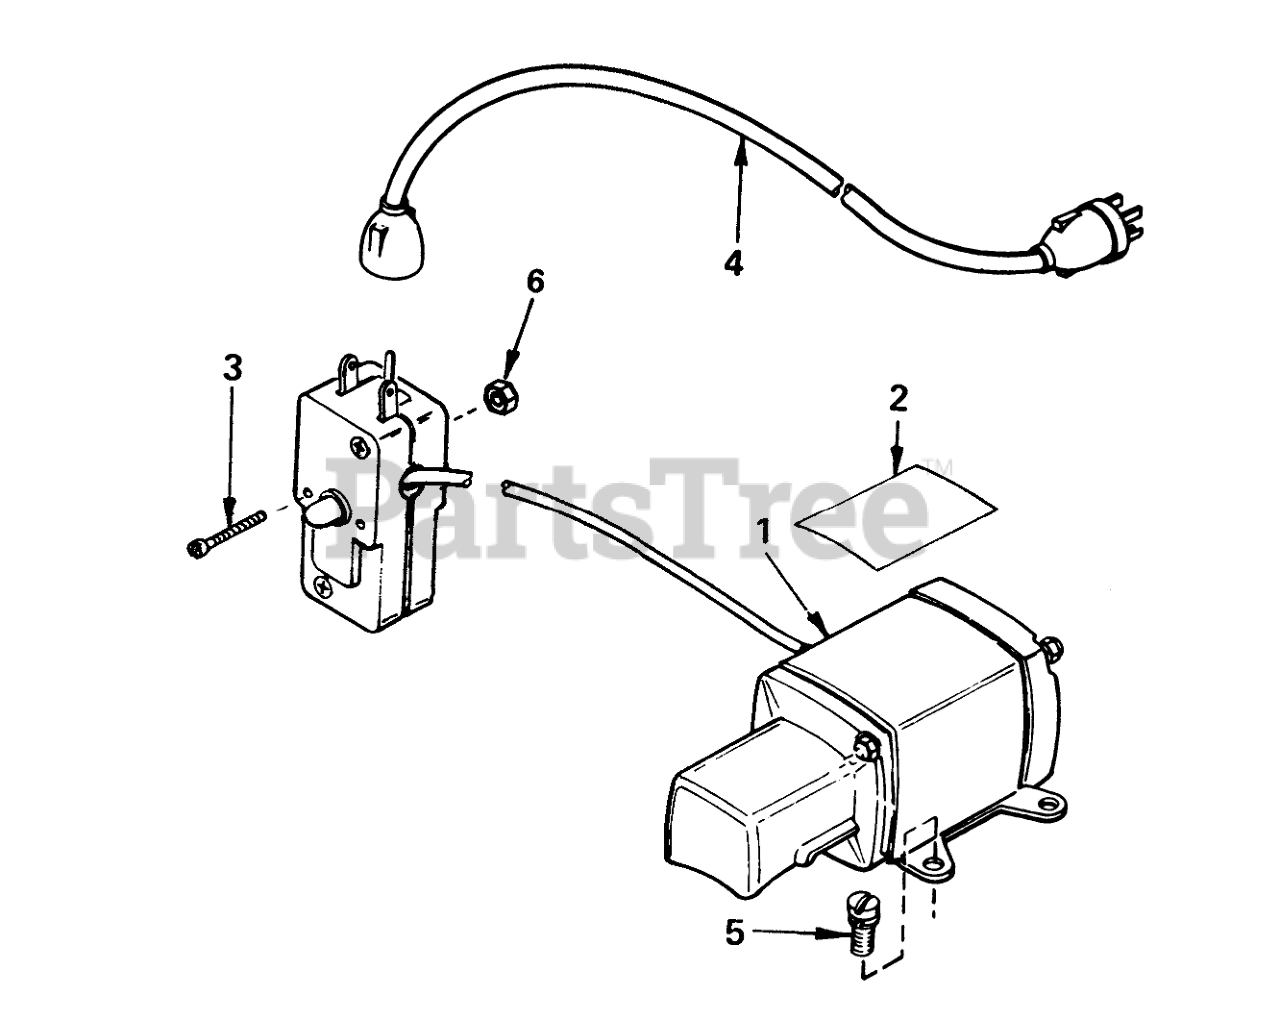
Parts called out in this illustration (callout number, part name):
1	Motor, Cranking (CSA Approved)(Incl. Ref. #2 thru 6)
2	Decal
3	Screw, Pan Hd.
4	Cord-Extension
5	Screw (T-30, 1/4-20 x 23/32)
6	Nut & Lockwasher
